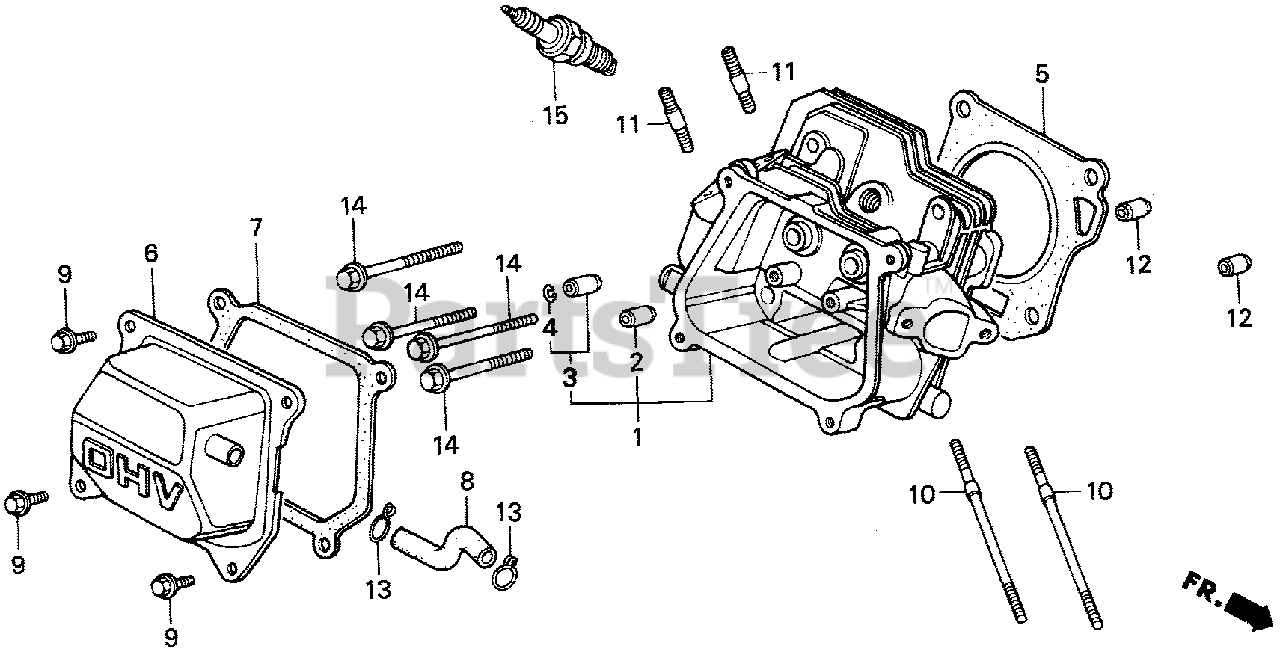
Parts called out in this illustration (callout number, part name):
1	CYLINDER HEAD
2	GUIDE, VALVE (OS)
3	GUIDE, EX. VALVE (OS)
4	CLIP, VALVE GUIDE
5	GASKET, CYLINDER HEAD
6	COVER, HEAD
7	GASKET, CYLINDER HEAD COVER
8	TUBE, BREATHER
9	BOLT, FLANGE (6X13)
10	BOLT, STUD (6X109)
11	BOLT, STUD (8X32)
12	PIN A, DOWEL (10X16)
14	BOLT, FLANGE (8X60)
15	SPARK PLUG (BPR5ES) (NGK)
15	SPARK PLUG (W16EPR-U) (DENSO)
15	SPARK PLUG (BPR6ES) (NGK)
15	SPARK PLUG (W20EPR-U) (DENSO)
